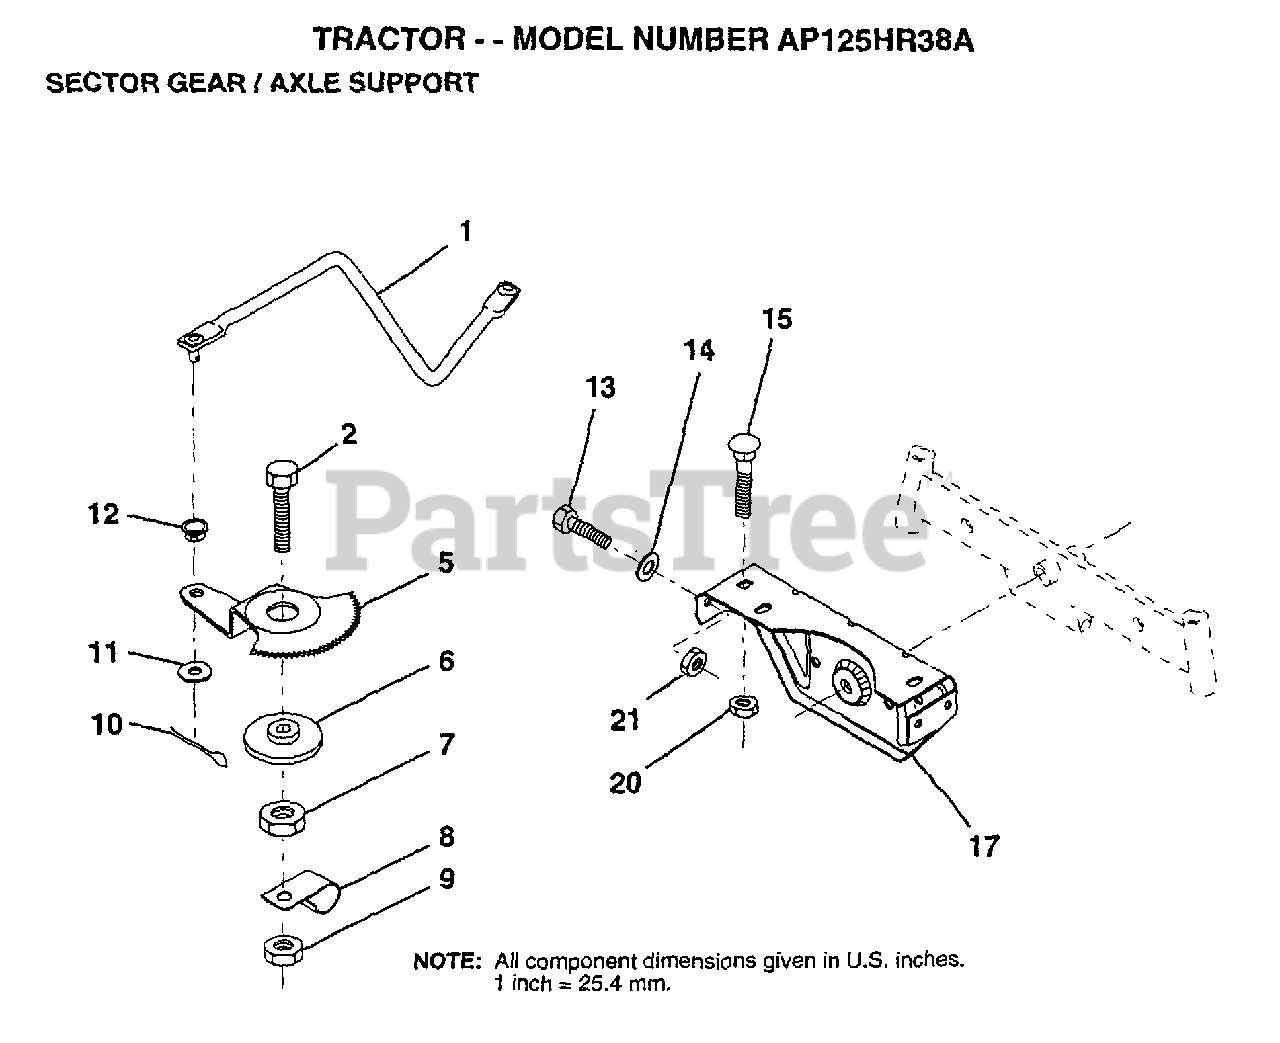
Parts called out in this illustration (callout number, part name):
1	DRAG LINK
2	"BOLT,HEX"
5	GEAR SECTOR
6	BUSHING
7	NUT
8	CLIP INSULATOR
9	NUT LTV
10	COTTER PIN
11	WASHER
12	BUSHING.DRAGLINK
13	BOLT
14	WASHER
15	BOLT
17	SUPT AXLE FRONT
